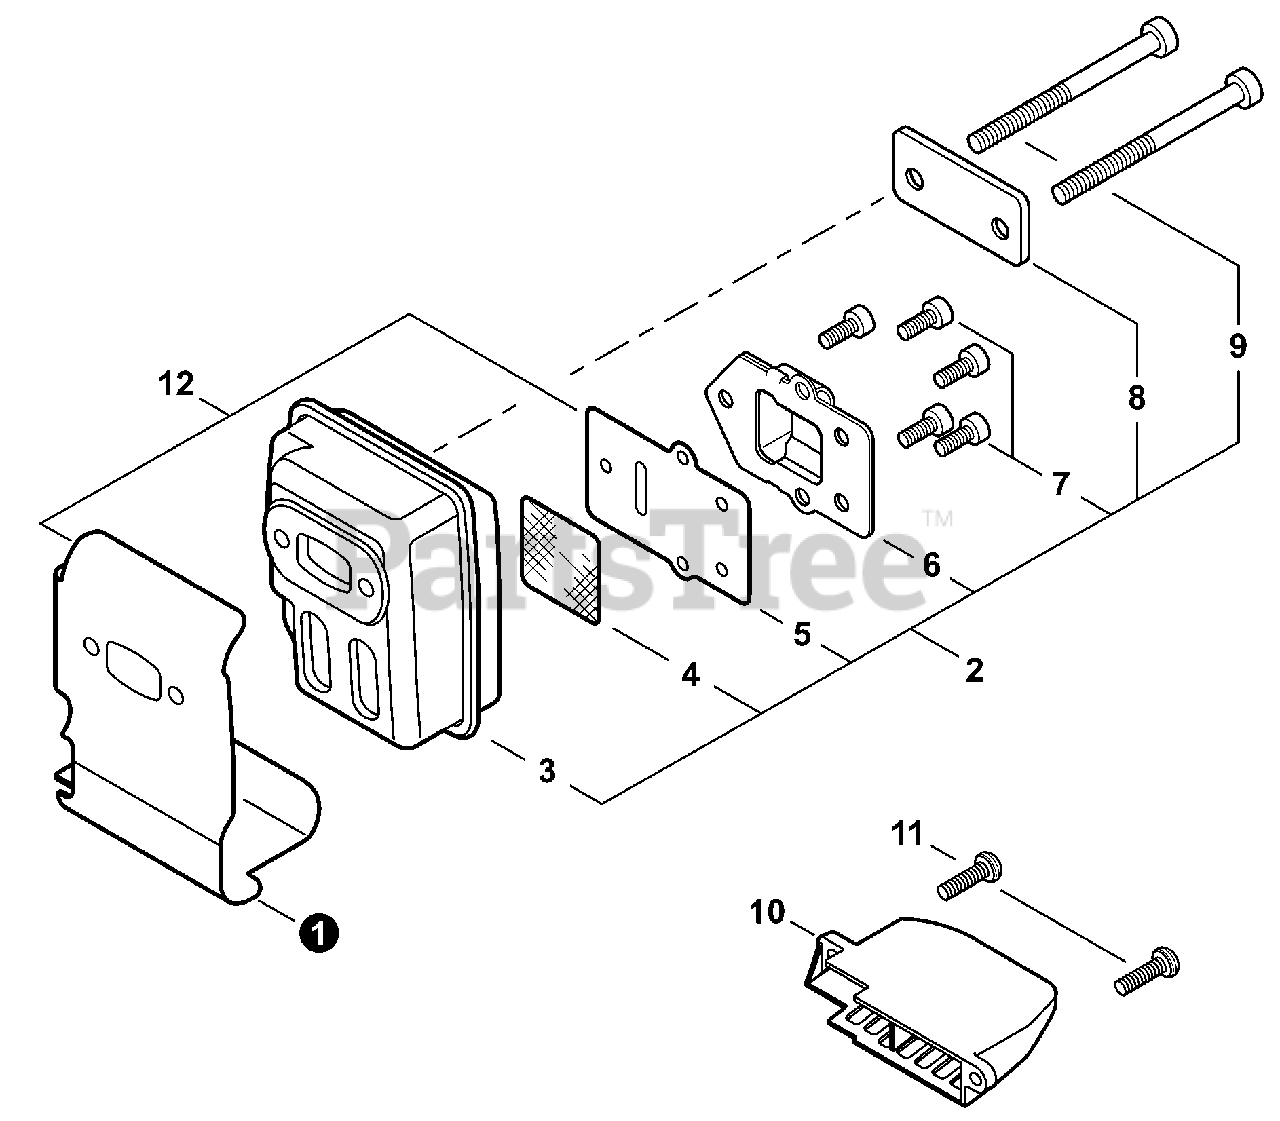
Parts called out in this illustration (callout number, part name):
1	SHIELD, EXHAUST
2	MUFFLER ASSY
3	MUFFLER
4	SCREEN, SPARK ARRESTER
5	GASKET, EXHAUST
6	GUIDE, EXHAUST
7	SCREW - 4×8 -- TORX
9	SCREW - 5×55
10	DUCT, AIR
11	SCREW - 5×16
12	GASKET KIT
